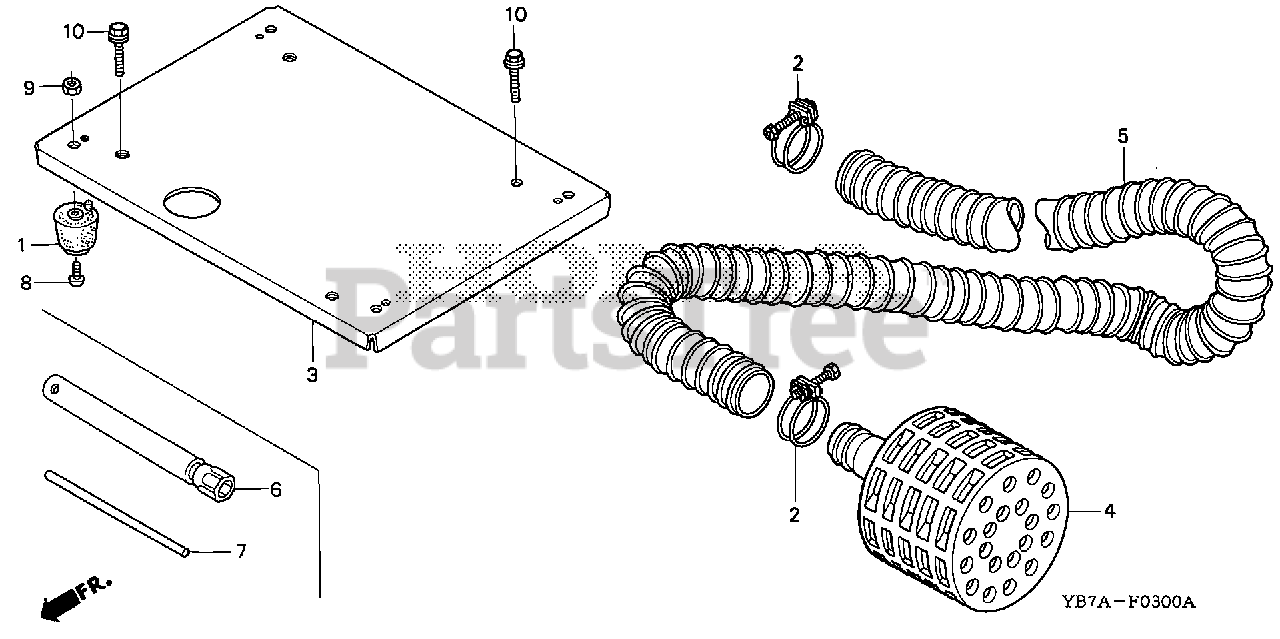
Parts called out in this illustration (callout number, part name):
1	RUBBER (LOWER)
2	BAND, HOSE
3	BED, FRAME
4	STRAINER (ENGINE NO.)
8	SCREW, PAN (6X10)
9	NUT, HEX. (6MM)
10	BOLT, FLANGE (8X32)
